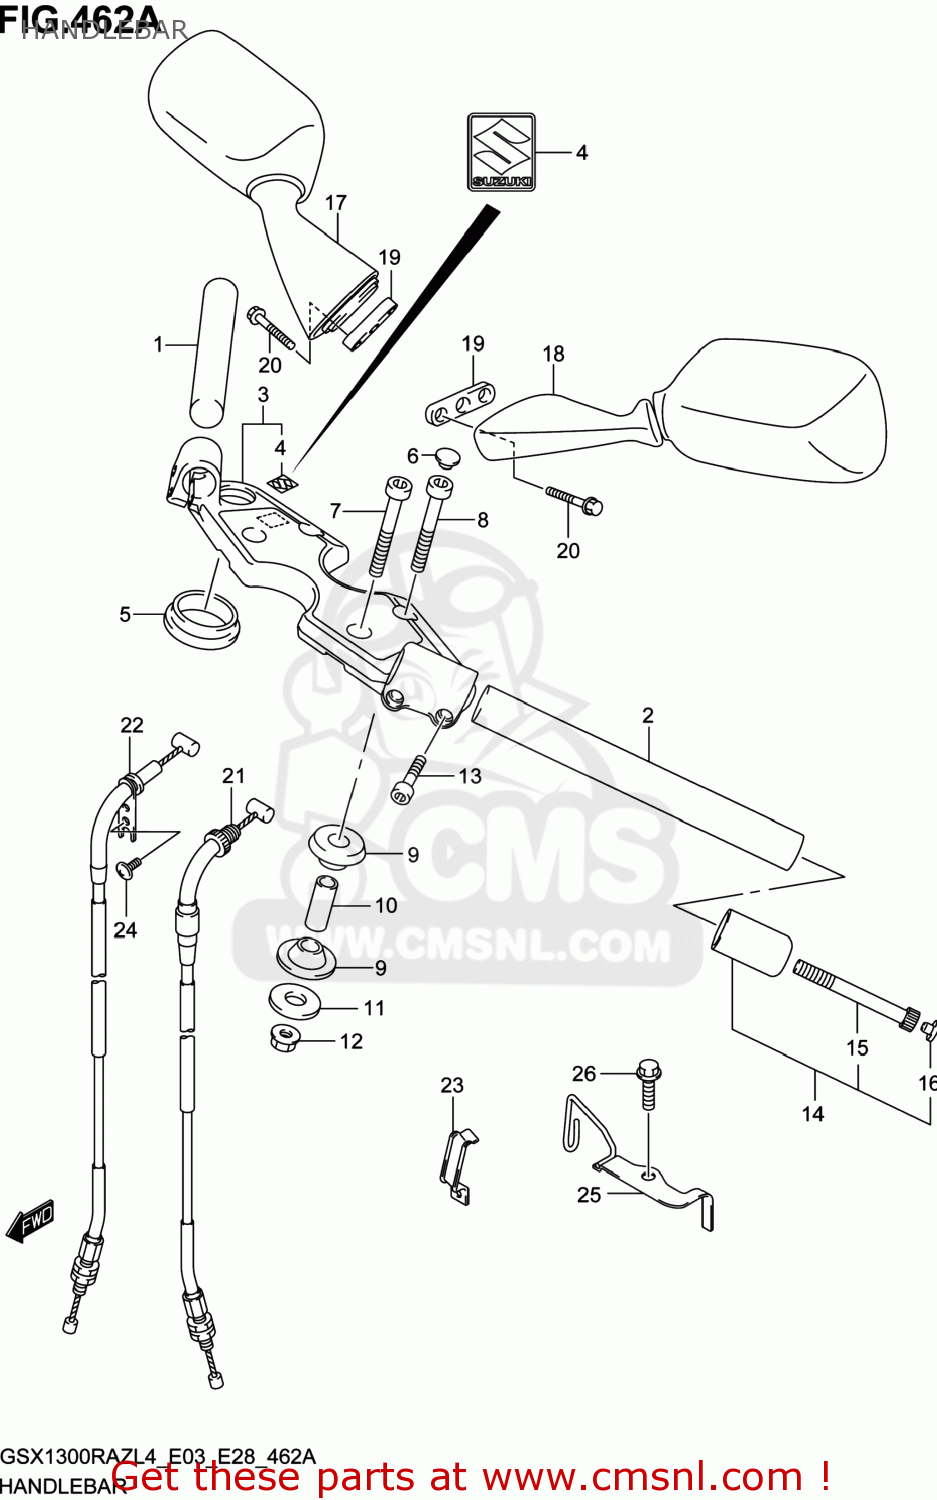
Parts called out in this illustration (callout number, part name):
1	HANDLEBAR,R
2	HANDLEBAR,L
3	HOLDER,HANDLEBAR
4	EMBLEM,"S"
5	CUSHION,HANDLE HOLDER
6	CAP,HANDLE HOLDER BRACKET BOLT
7	BOLT
8	BOLT
9	CUSHION,UPR BRACKET
10	SPACER,STEERING STEM HEAD
11	WASHER(10.5X30X3.2)
12	NUT
13	BOLT(6X25)
14	BALANCER SET,HANDLEBAR
15	BOLT
16	CAP(OD:10)
17	MIRROR ASSY,RR VIEW,R
18	MIRROR ASSY,RR VIEW,L
19	CUSHION,RR VIEW MIRRORR
20	BOLT
21	CABLE ASSY,THROTTLE NO.1
22	CABLE ASSY,THROTTLE NO.2
23	GUIDE,CABLE
24	SCREW(5X10)
25	GUIDE,CABLE
26	BOLT
